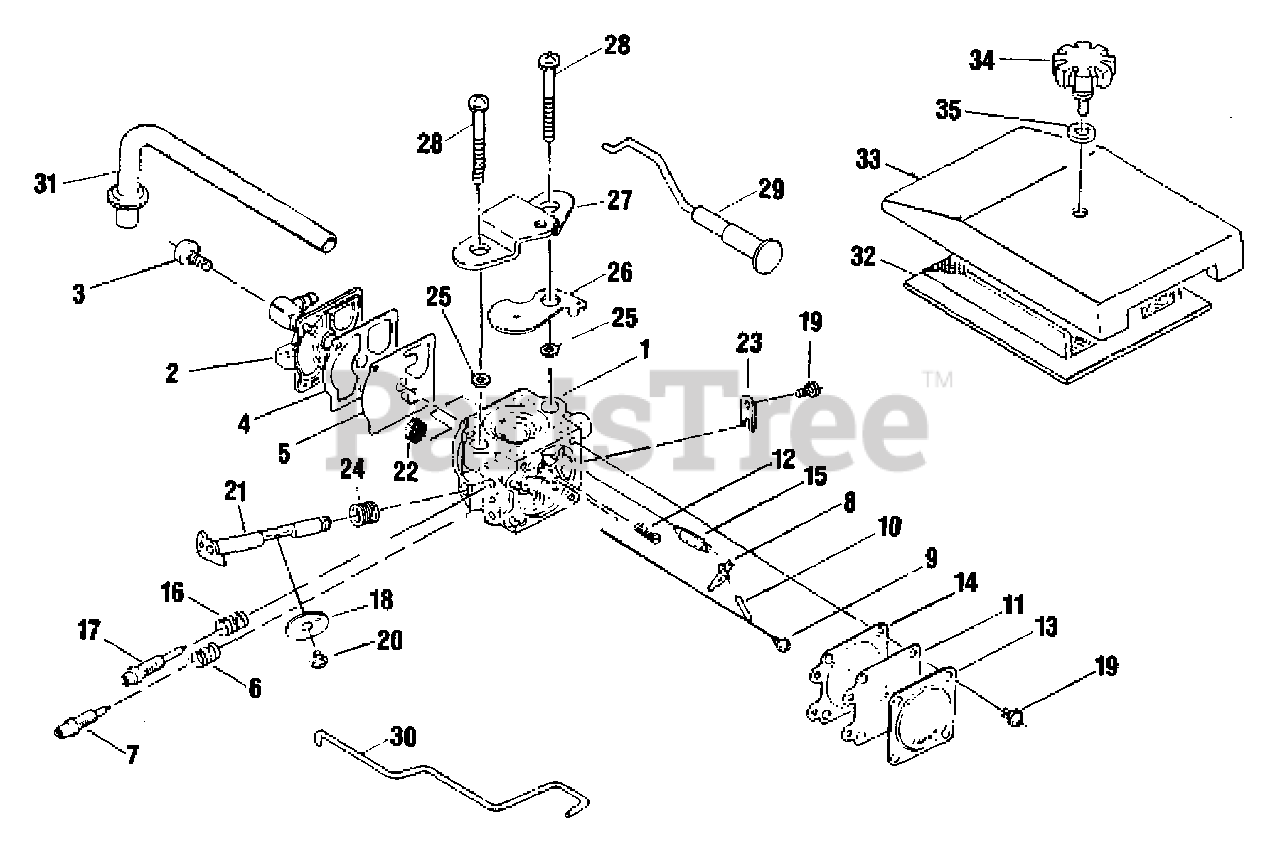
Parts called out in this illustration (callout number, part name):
1	BODY, CARBURETOR
2	COVER ASSY, PUMP
3	SCREW
4	GASKET, PUMP
5	DIAPHRAGM, PUMP
6	SPRING, NEEDLE
7	NEEDLE, LOW SPEED
8	LEVER, METERING
9	SCREW, METERING LEVER PIN
9	SCREW
10	PIN, METERING LEVER
10	PIN
11	DIAPHRAGM, METERING
11	DIAPHRAGM ASSY
12	SPRING
12	LEVER, SPRING
13	COVER, METERING DIAPHRAGM
14	GASKET, METERING DIAPHRAGM
14	GASKET, DIAPHRAGM
15	VALVE, INLET NEEDLE
16	SPRING, NEEDLE
17	NEEDLE, HIGH SPEED
18	VALVE, THROTTLE
19	SCREW
20	SCREW
21	SHAFT
22	SCREEN, FUEL INLET
22	STRAINER
23	CLIP, THROTTLE SHAFT
24	SPRING, THROTTLE RETURN
25	WASHER 5
26	PLATE, CHOKE
27	BRACKET
28	SCREW
29	ROD, CHOKE
30	ROD, THROTTLE
31	PIPE, PULSE
32	FILTER, AIR - FLOCKED
33	COVER, AIR FILTER
34	THUMBSDREW
35	O-RING
